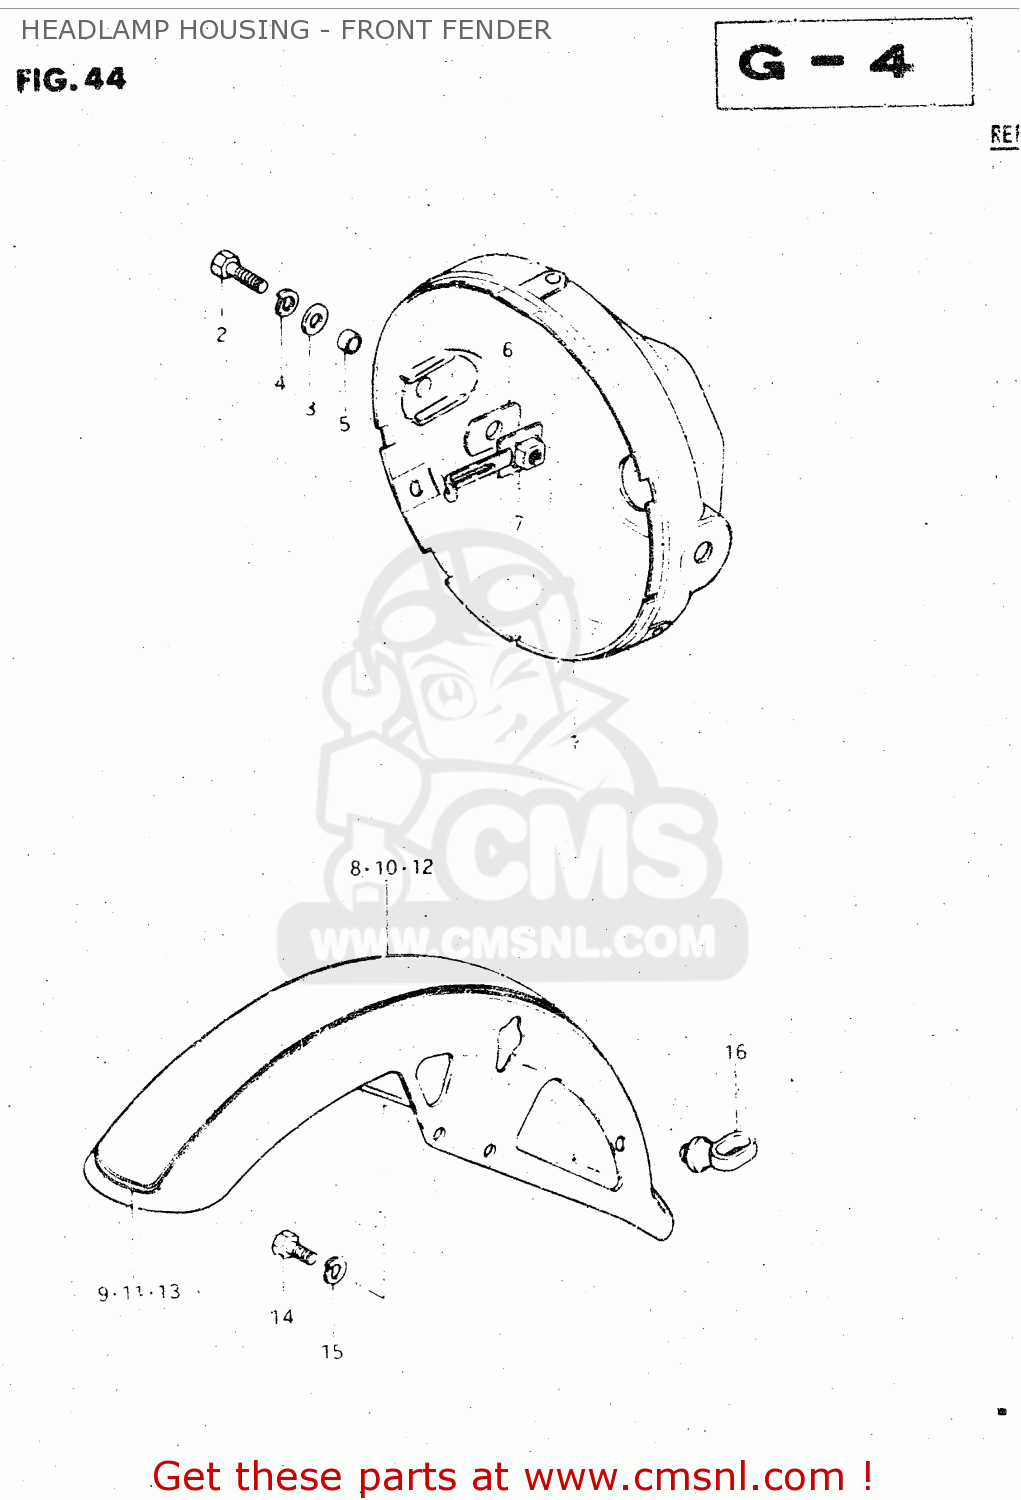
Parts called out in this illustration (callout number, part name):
1	HOUSING,HEADLAMP
2	BOLT
3	WASHER
4	LOCK WASHER
5	SPACER (8.8X12X7)
6	CUSHION
7	PLATE,HEADLAMP HOUSING
8	FENDER, FRONT
9	TAPE
10	FENDER, FRONT (RED)
11	TAPE,FRONT FENDER
12	FENDER, FRONT
13	TAPE
14	BOLT
15	LOCK WASHER
16	GUIDE,CABLE
